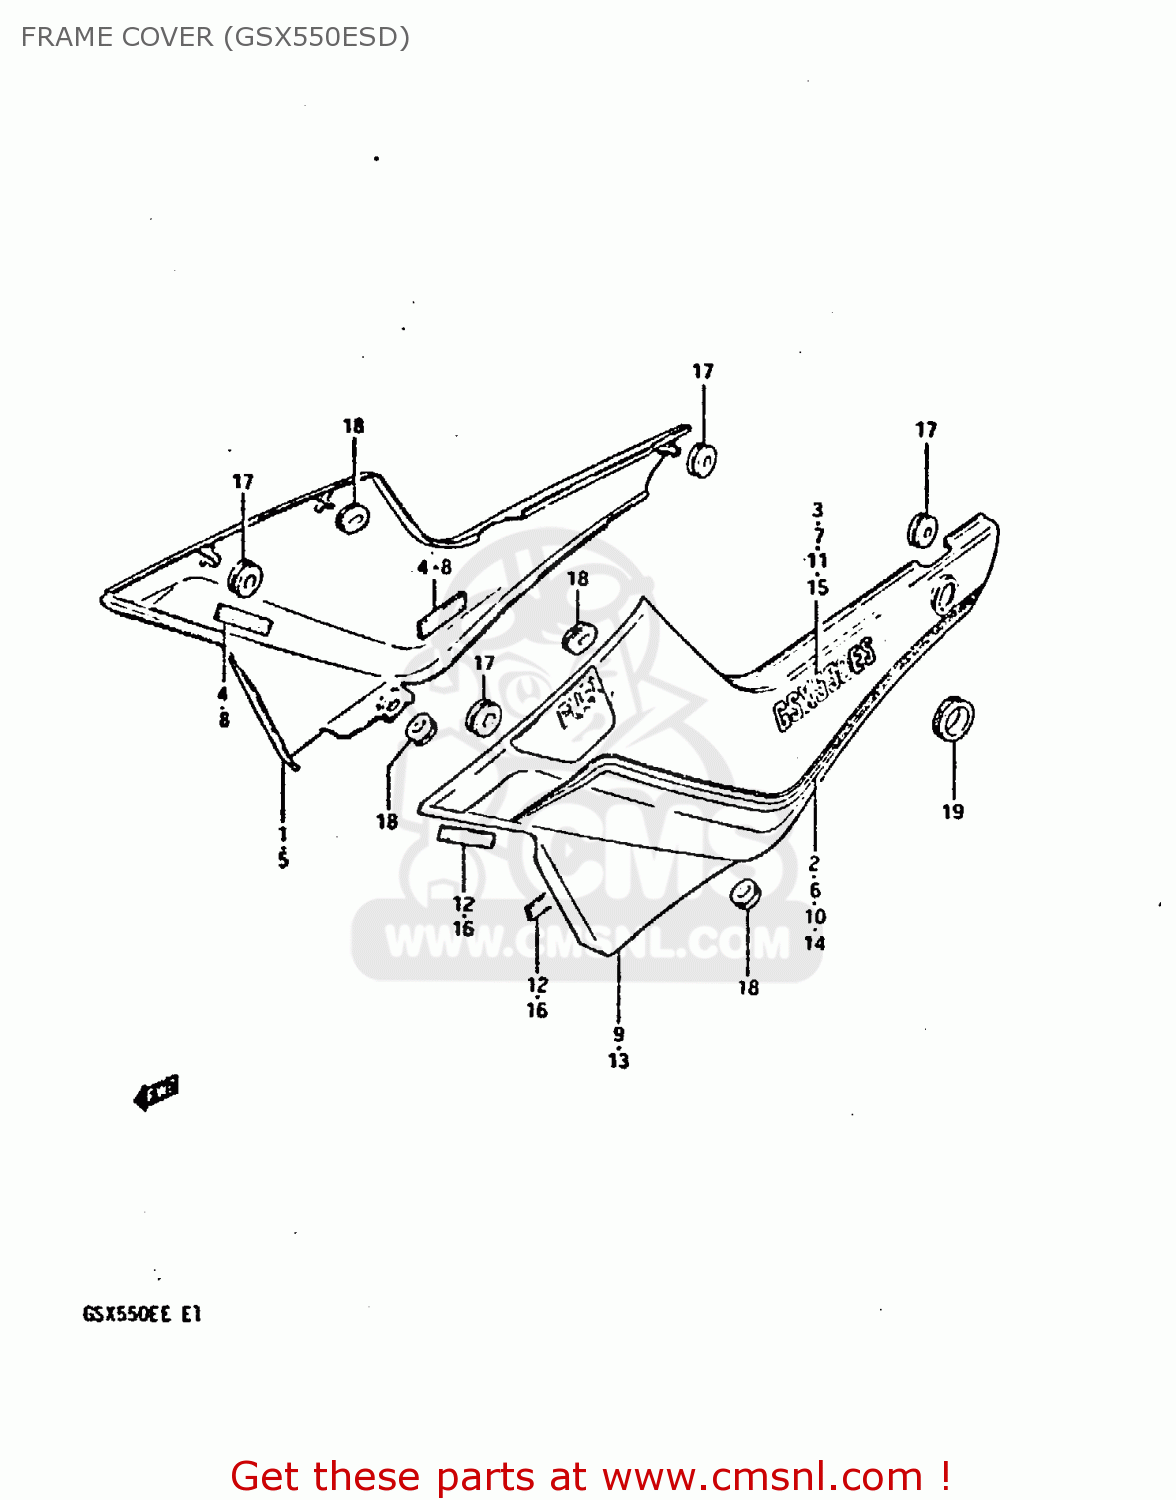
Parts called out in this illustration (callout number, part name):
1	COVER SET, FRAME RH
2	TAPE SET,FRAME COVER
3	EMBLEM
4	RUBBER,FRAME COVER
5	COVER SET, FRAME RH
6	TAPE SET,FRAME COVER
7	EMBLEM
8	RUBBER,FRAME COVER
9	COVER SET, FRAME LH
10	TAPE SET,FRAME COVER
11	EMBLEM
12	RUBBER,FRAME COVER
13	COVER SET, FRAME LH
14	TAPE SET,FRAME COVER
15	EMBLEM
16	RUBBER,FRAME COVER
17	CUSHION
18	CUSHION
19	GROMMET,SEAT LOCK HOLE
